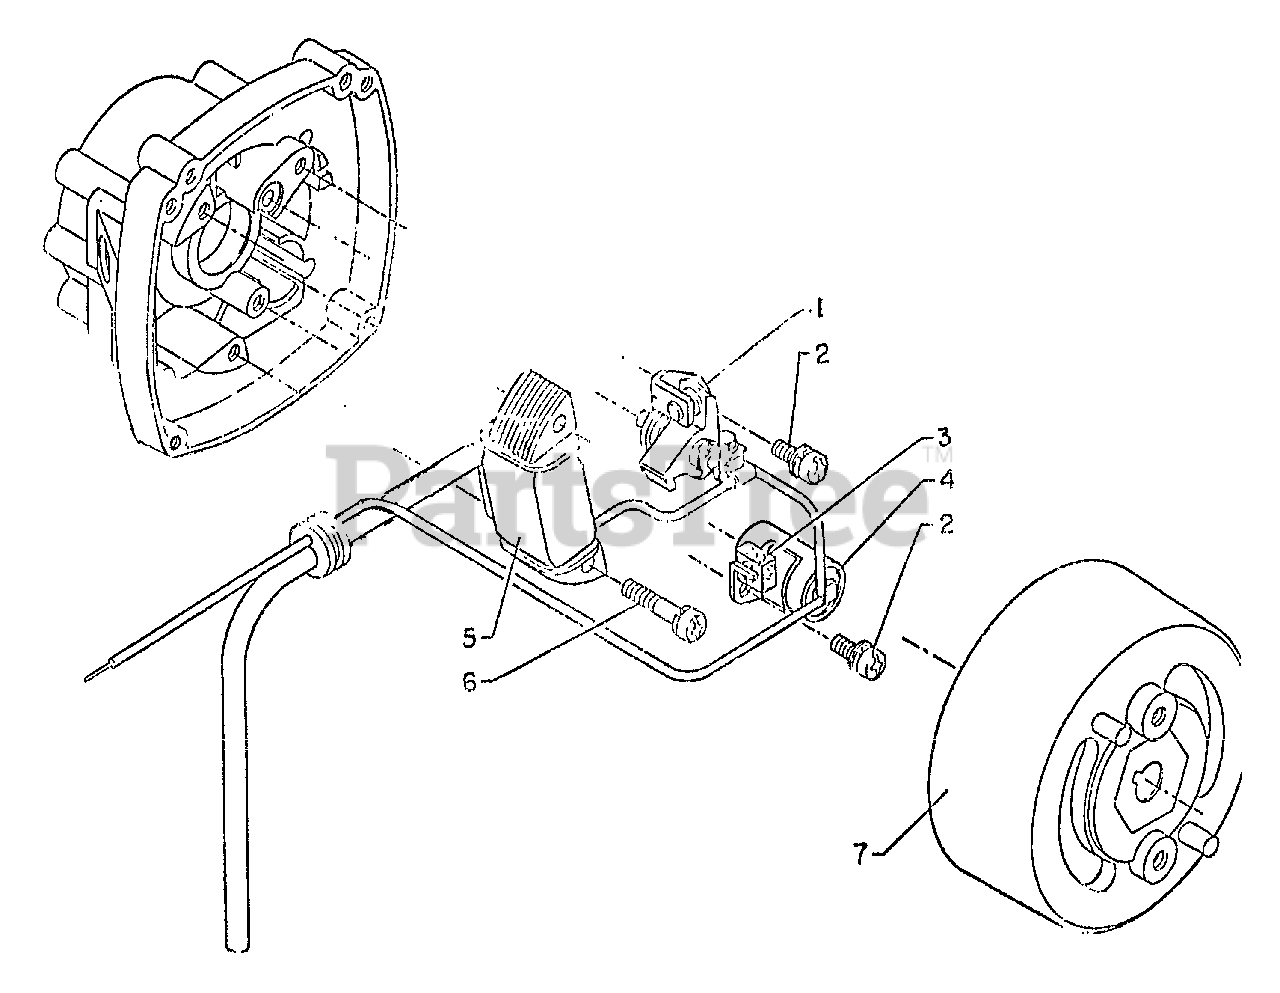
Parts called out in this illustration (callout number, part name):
1	CONTACT POINT SET
2	SCREW - 4X10
2	LOCKWASHER - 4
2	WASHER - 4
3	PAD, OIL
4	CONDENSER
5	COIL, IGNITION
6	SCREW - 4X24
6	LOCKWASHER - 4
7	FLYWHEEL
